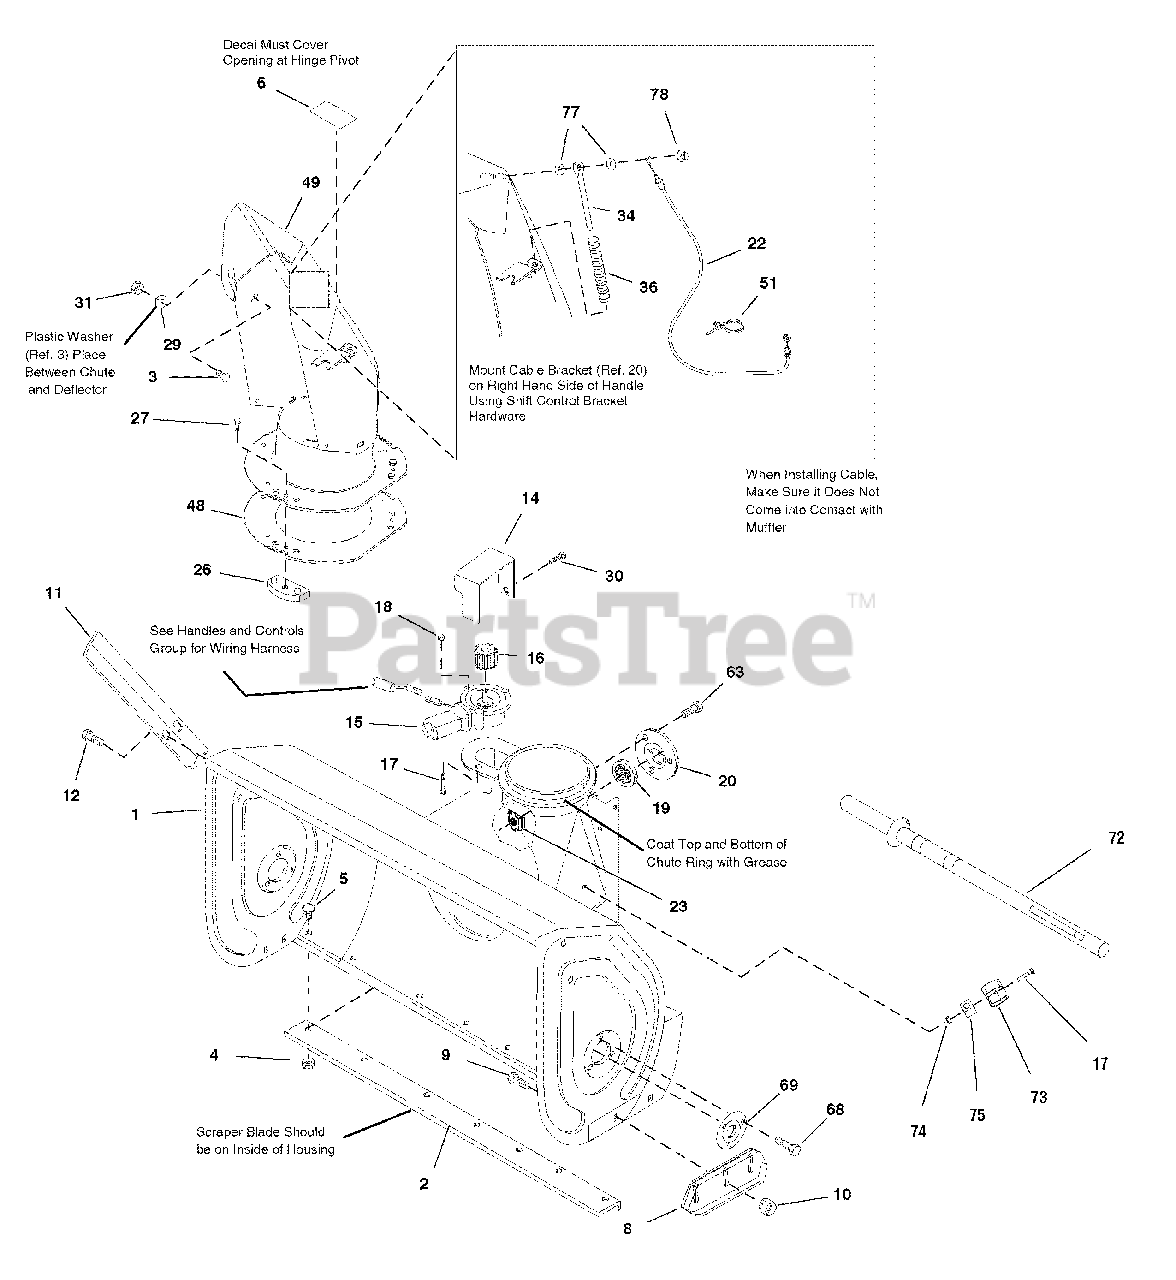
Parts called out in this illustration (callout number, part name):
1	HOUSING ASSEMBLY, 24"
1	HOUSING ASSEMBLY, 28"
1	HOUSING ASSEMBLY, 32"
1	HOUSING ASSEMBLY, 38"
2	BLADE, Scraper for 24"
2	BLADE, Scraper for 28"
2	BLADE, Scraper for 32"
2	BLADE, Scraper for 38"
3	CARRIAGE BOLT, 5/16-18 x 3/4, G5
4	NUT, Hex Flange, 5/16-18 Two-Way Lock
5	CARRIAGE BOLT, 5/16-18 x 5/8, G5
6	DECAL, Orange Strip Hinge Snow Chute
8	SKID SHOE
9	CARRIAGE BOLT, 3/8-16 x 3/4, G5
9	CARRIAGE BOLT, 3/8-16 x 1, G5
10	NUT, Hex Flange, 3/8-16 ESNA
11	CUTTER, Drift w/Tabs
12	SCREW, Hex Washer Head Taptite, 5/16-18 x 3/4
14	COVER, Gear
15	MOTOR, Spout Rotator, 38/42"
16	PINION, 1.417 OD .296 Slot 1-1/4 Long 16T Powdered Metal
17	SCREW, Hex Washer Head Slot, #10C x 1-1/4, G2
18	NUT, Hex Whiz Lock Flange, #10-24
19	BEARING, 3/4 ID x 1.78 OD x .61 Long Greased
20	BEARING RETAINER
22	CABLE & KNOB ASSEMBLY
23	RETAINER, Nut, 5/16-18 .057/.092
26	HOLD DOWN, Chute, Nylon
27	SCREW, Hex Washer Head Taptite, 10-14 x 5/8
29	WASHER, Nylon, .388 x 1.12 x .03
30	SCREW, Hex Washer Head Taptite, 1/4-20 x 3/8
31	NUT, Hex Flange, 5/16-18 ESNA
34	ROD, Spring
36	SPRING, Compression
48	GEAR, Chute, 10 OD 6.65 ID .105 Thick
49	CHUTE ASSEMBLY, with Pigtail Orange
51	TIE, Self Locking, .184 Wide 7.31 Long
63	SCREW, Hex Whiz Lock Flange, 5/16-18 x 3/4
69	BEARING, Ball
72	STICK, Snow Cleanout w/Brush, Plastic
73	CLIP, Retainer
74	NUT, Hex Lock, 10-24 w/Nylon Insert
75	BLOCK, Universal Pivot
78	NUT, Push
